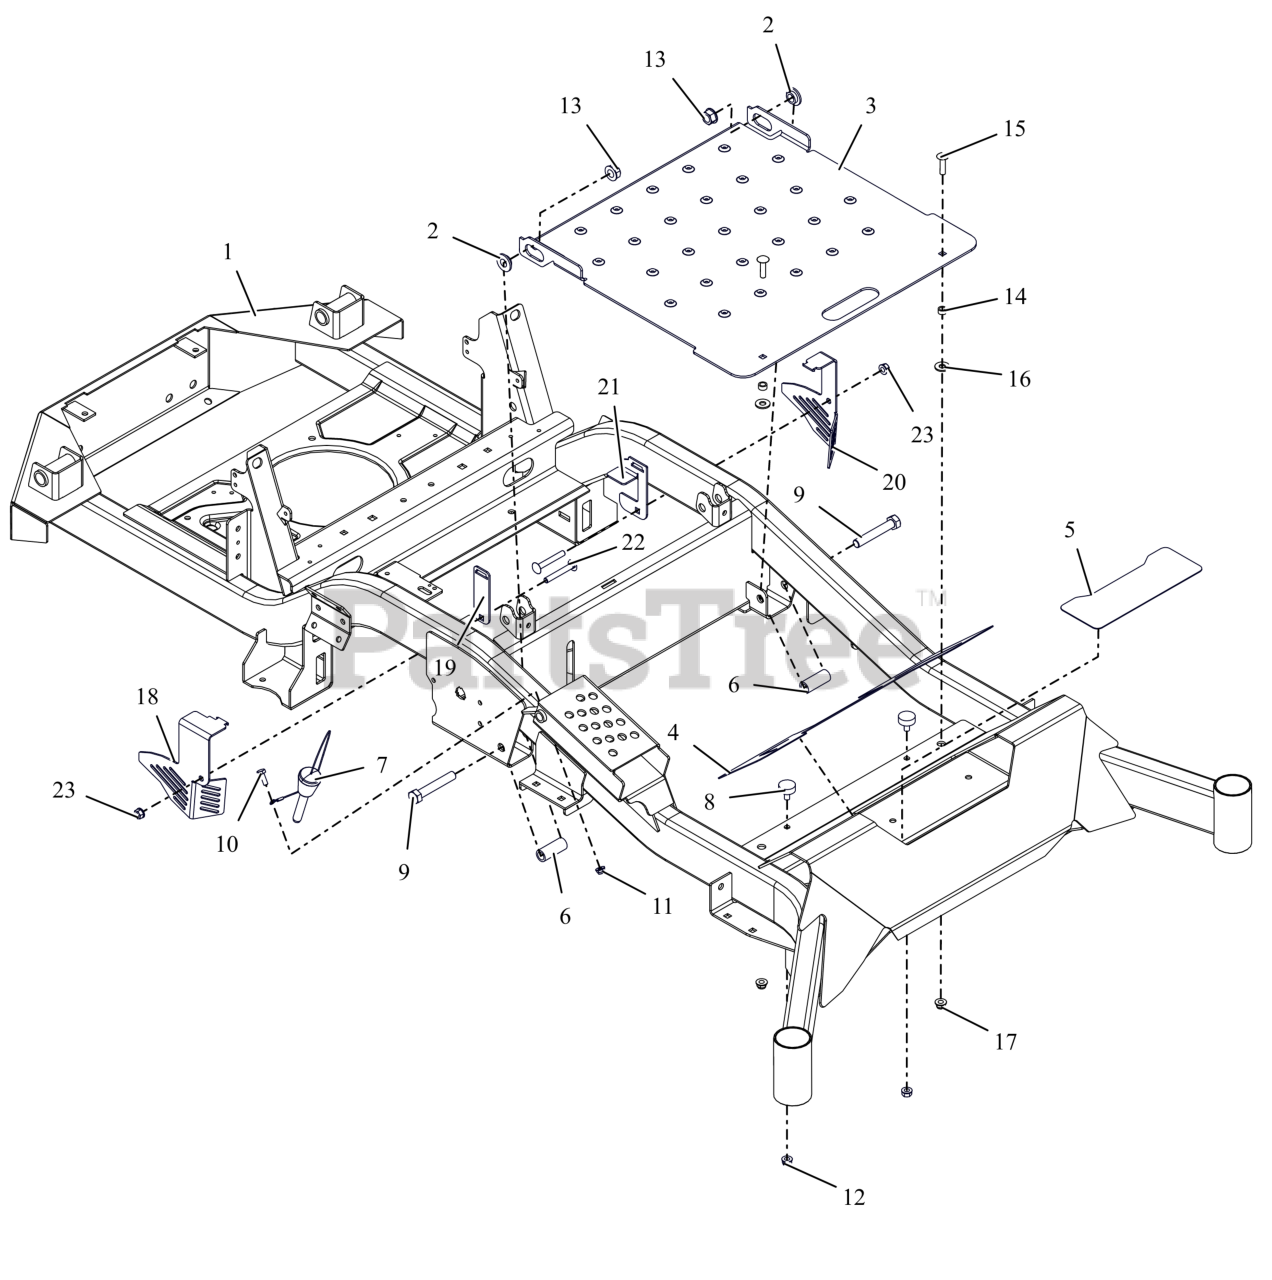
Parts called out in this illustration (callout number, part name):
1	APEX 60"FRAME W/SAFETY DECALS
2	BSHG-FLG .515X.750X.395X1.120
3	PANEL, ACCESS
4	GRIP, FRONT
5	GRIP, STEP
6	SPACER, .515X.75X1.83
7	PIN, MAGNETIC .50X2.50
8	BUMPER, RUBBER
9	BLT, HEX .50-13X3.00 G5 ZCC
10	BLT, HEX .25-20X.75 G5 ZCC
11	NUT,NYL-FLG .25-20 GF ZCC
12	NUT,SPNLK-FLG .31-18 G5 ZCC
13	NUT-LK-TOP-FLG .500-13 GF ZCC
14	BSHG-SLV .344 X .500 X .260
15	BLT, RHSSN.31-18X1.25 G5 ZCC
16	WSHR,FLT .375X.875X.083 ZCC
17	NUT,LK-NYL-FLG .31-18 G5ZC120
18	GUARD, TRANSAXLE FAN - RH
19	BRKT, TRANSAXLE FAN GUARD
20	BRKT, TRANSAXLE FAN GUARD-LH
21	MOUNT, TRANSAXLE GUARD
22	BLT, RHSSN.31-18X2.25 G5 ZCC
23	NUT,LK-CTR-FLG .31-18 GF ZCC
